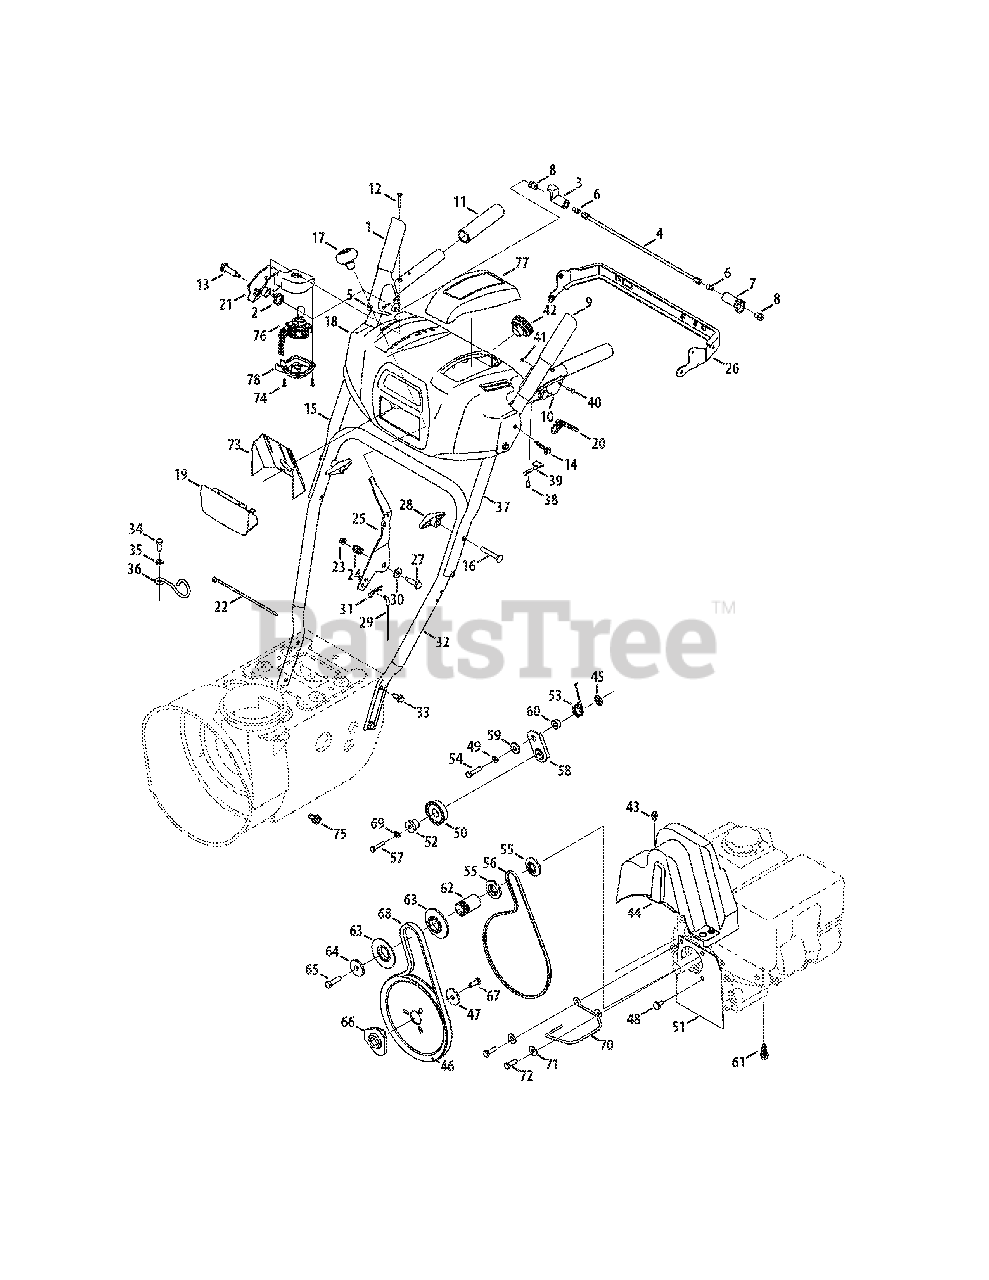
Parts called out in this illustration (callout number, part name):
1	Handle Engagement Ass’y RH
2	Torsion Spring
3	Lock Plate
4	Pivot Rod
5	Rubber Bumper
6	Screw, 1/4-20 x .500
7	Clutch Lock Cam
8	Shoulder Nut, 1/4-20
9	Handle Engagement Assembly LH
10	Handle Clutch Lock LH Assembly
11	Handle Grip
12	Screw, #10-24 x 0.375
13	Shoulder Screw, 1/4-20
14	Screw, 1/4-20 x 1.625
15	Upper Handle RH
16	Carriage Screw, 5/16-18 x 2.25
17	Shift Knob
18	Handle Panel, includes Ref. 19 & 73
20	Steering Control
21	Handle Clutch Lock RH Assembly
22	Cable Tie
23	Flange Lock Nut, 1/4-20
24	Compression Spring
25	Shift Lever
26	Panel Bracket
27	Shoulder Screw
28	Wing Knob
29	Speed Selector Cable
30	Flat Washer
31	Click Pin
32	Lower Handle
33	Screw, 5/16-18 x 0.75
34	Screw, M8-1.25
35	Flat Washer, .330 x .630 x .0635
36	Cable Control Wire
37	Upper Handle LH
38	Screw, #8-16 x 0.50
39	Clutch Lock Spring
40	Pin, 3/16
41	Retainer Ring
42	Headlight Socket
43	AB Screw, 1/4-20 x 0.625
44	Belt Cover
45	Push-on Nut
46	Auger Pulley
47	Flat Washer
48	Shoulder Screw
49	Lock Washer
50	Idler Pulley Assembly
51	Plt., Cvr.
52	Spacer
53	Torsion Spring
54	Hex Screw, 5/16-24 x 1.25
55	Pulley Half
56	Belt, Wheel Drive
57	TT Screw, 1/4-20 x 1.25
58	Drive Clutch Idler Bracket
59	Shoulder Spacer
61	TT Sems Screw, 3/8-16 x 1.0
62	Spacer
63	Pulley Half
64	Flat Washer
65	Hex Bolt, 3/8-24 x 1.25
66	Pulley Adapter
67	Hex Bolt, 5/16-24 x 0.875
68	V-Belt,.500 x 35.00 Lg
69	Lock Washer
70	Belt Guide
71	Flat Washer, .349 x .879 x .063
72	Screw, 5/16-24 x 1.00
73	Lens Label
74	Screw, .159 OD x .610
75	Screw (For ground wire)
76	Electric Chute Harness
77	Handle Panel Cover
78	Joystick Housing Cover
